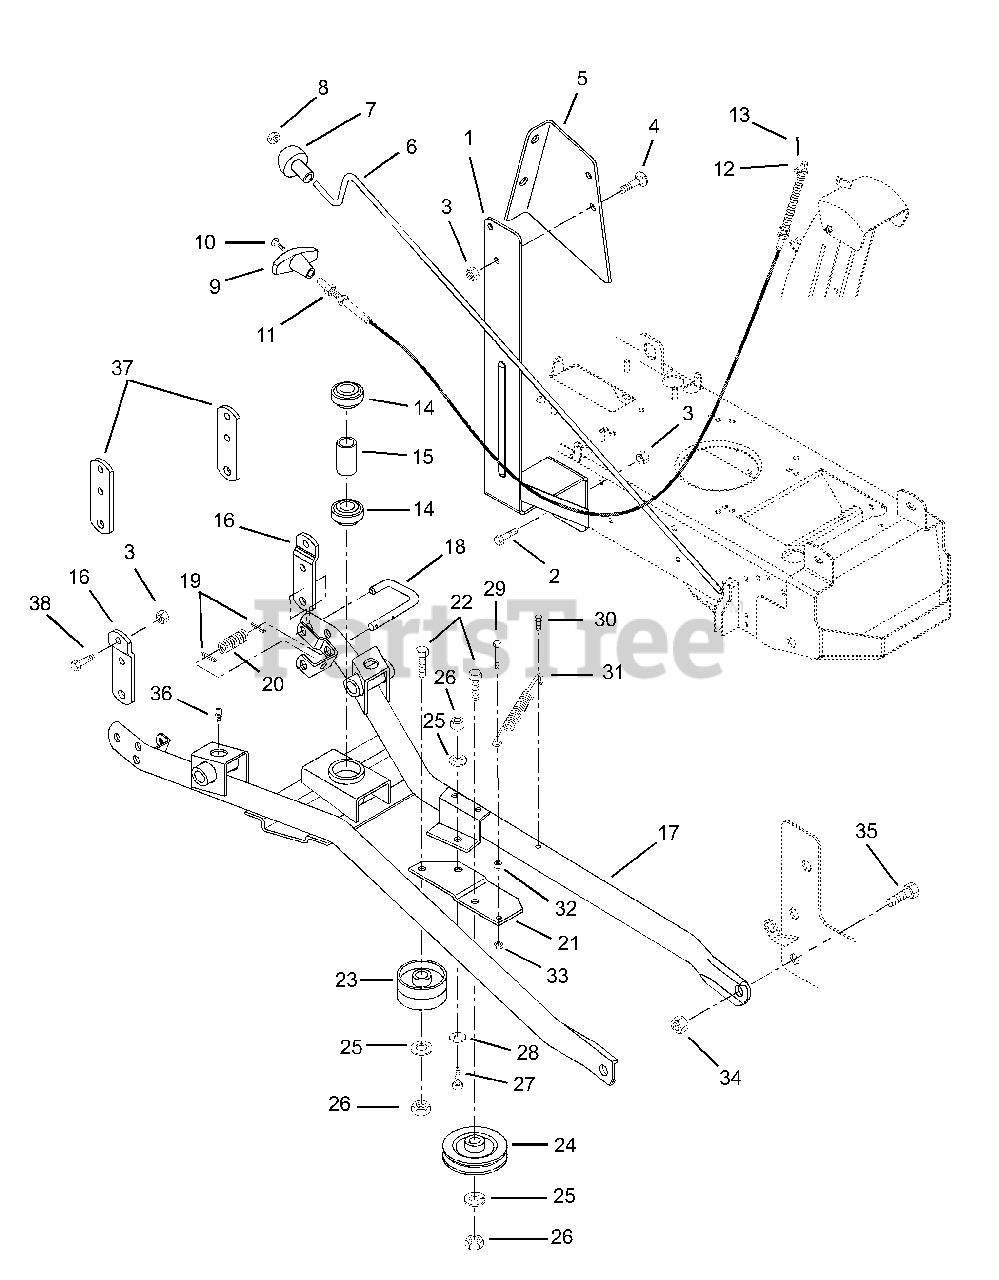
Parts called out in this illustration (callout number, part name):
1	Support - Control Bracket
2	Bolt-Hex .38-16 x .75 Grade 5
3	Nut-Locking Top .375-16
3	Nut-Locking-Top .375-16
4	Bolt-Round Head Square Neck .38-16 x .75 Grade 5
5	Control Bracket
6	Chute Control Crank
7	Knob
8	Nut-Locking-Jam Center .38-16
9	Knob-Black
10	Screw-Machine 8-32 x .75
11	Control Cable
13	Pin-Cotter .09 x .75
14	Bearing-Ball .750 x 1.781 x .61
15	Spacer
16	Hanger Bracket-Offset
17	Carriage Frame w/Spindle & Bearings
18	Latch Pin
19	Pin-Roll .125 x .75
20	Spring-Compression .047 x .28 x 5.05
21	Idler Arm
22	Bolt-Hex .38-16 x 1.75 Grade 2
23	Idler-Flat 2.25 x .38
24	Idler - V 3.06 x .38
25	Washer-Lock .375 x .115
26	Nut-Hex .375-16 Grade 2
27	Shoulder Bolt
28	Washer-Flat-Steel .511 x 1.441 x .125
29	Screw-Tapping 10-24 x 1.0
30	Screw-Tapping .312-18 x .75
31	Spring-Tension .090 x .75 x 3.50
32	Nut-Hex 10-24
33	Nut-Locking-Nylon 10-24
34	Nut-Locking-Center .62-11
35	Bolt-Hex .62-11 x 1.50 Grade 5
36	Fitting-Lube .25-28 x .256
37	Hanger Bracket
38	Bolt-Hex .38-16 x 1.00
